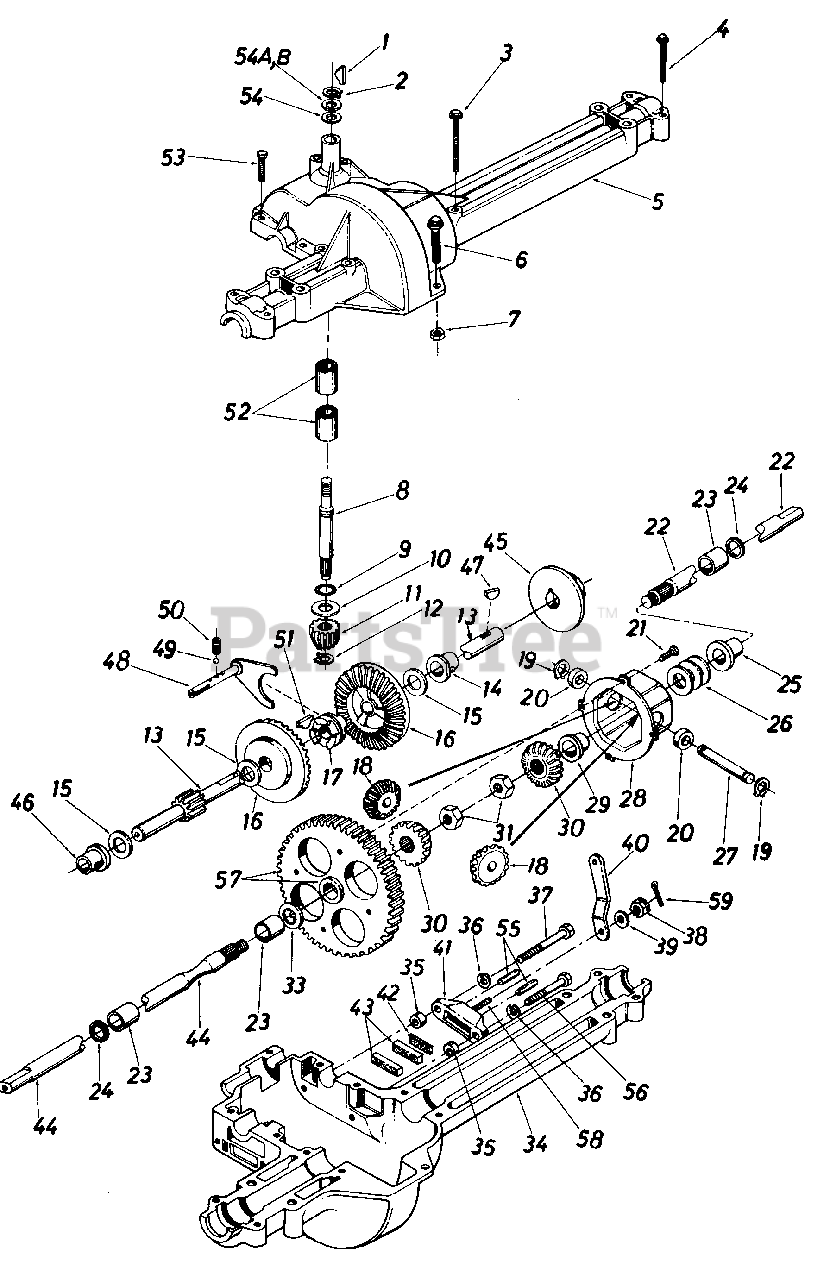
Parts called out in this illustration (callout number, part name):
1	#4 Hi-Pro Key 3/32 x 5/8" Dia.
2	Snap Ring .625" Shaft
3	Hex Bolt 1/4-20 x 1.75" Lg.
4	Hex Bolt 1/4-20 x 1.25" Lg.
5	Upper Housing
6	Hex Fl-Bolt 1/4-20 x .75" Lg.
7	Hex Nut 1/4-20 Thd.
8	Input Shaft
9	Square Seal 5/8" I.D.
10	Thrust Washer 5/8" I.D. x 1.25" O.D.
11	Pinion Input 14T
12	Retaining Ring 7/16" Ext.
13	Drive Shaft-R.H.
14	Flange Brg. 5/8" I.D. x 3/4" Lg.*
15	Fl-Wash.
16	Bevel Gear 42T
17	Clutch Collar
18	Miter Gear 15T
19	Snap Ring
20	Thrust Bearing 1/2" I.D. x 1.0" O.D.
21	Pan Head Scr. 1/4-20 x .50" Lg. w/Patch
22	Axle R.H.
23	Sleeve Bearing 3/4" I.D. x 1.0" Lg.
24	Oil Seal 3/4" I.D.
25	Flange Bearing 3/4" I.D. x 15/16" Lg.
26	Fl-Wash. .760" I.D. x 1.49" O.D.
27	Cross Shaft
28	Differential Housing Ass'y.
30	Miter Gear
31	Hex Ins. L-Nut 1/2-20 Thd.
33	Fl-Wash. .75" I.D. x 1.5" O.D.
34	Lower Housing
35	Spacer .53" O.D. x 3/8" Lg.
36	L-Wash. 1/4" I.D.
37	Hex Bolt 1/4-20 x 1.50" Lg. (Grade 5)
38	Castle Nut 5/16-24 Thd.
39	Fl-Wash. .34" I.D. x .875" O.D.
40	Actuating Arm-R.H.
41	Brake Yoke
42	Puck Plate
43	Brake Puck
44	Axle L.H.
45	Brake Disc
46	Flange Bearing 5/8" I.D. x 15/16" Lg.
47	Woodruff Key 3/16 x 5/8 HT
48	Shift Fork Ass'y.
49	Ball Detent .250" Dia.
50	Spring Detent
51	#9 Hi-Pro Key 3/16" x 3/4" Dia. HT
52	Needle Brg. 5/8" I.D. x 1/2" Lg.
53	Hex Bolt 1/4-20 x 1.00" Lg.
54	Fl-Wash. 5/8" I.D. x .030
54A	Fl-Wash. 5/8" I.D. x .040
54B	Fl-Wash. 5/8n I.D. x .020
55	Actuating Pin 5/16" Dia.
56	Hex Bolt 1/4-20 x 1.50" Lg. (Grade 5)
57	Differential Gear 72T Ass'y. w/ Bearing
58	Sq. Hd. Bolt 5/16-24 Thd.
59	Cotter Pin 3/32" Dia. x .50" Lg.
